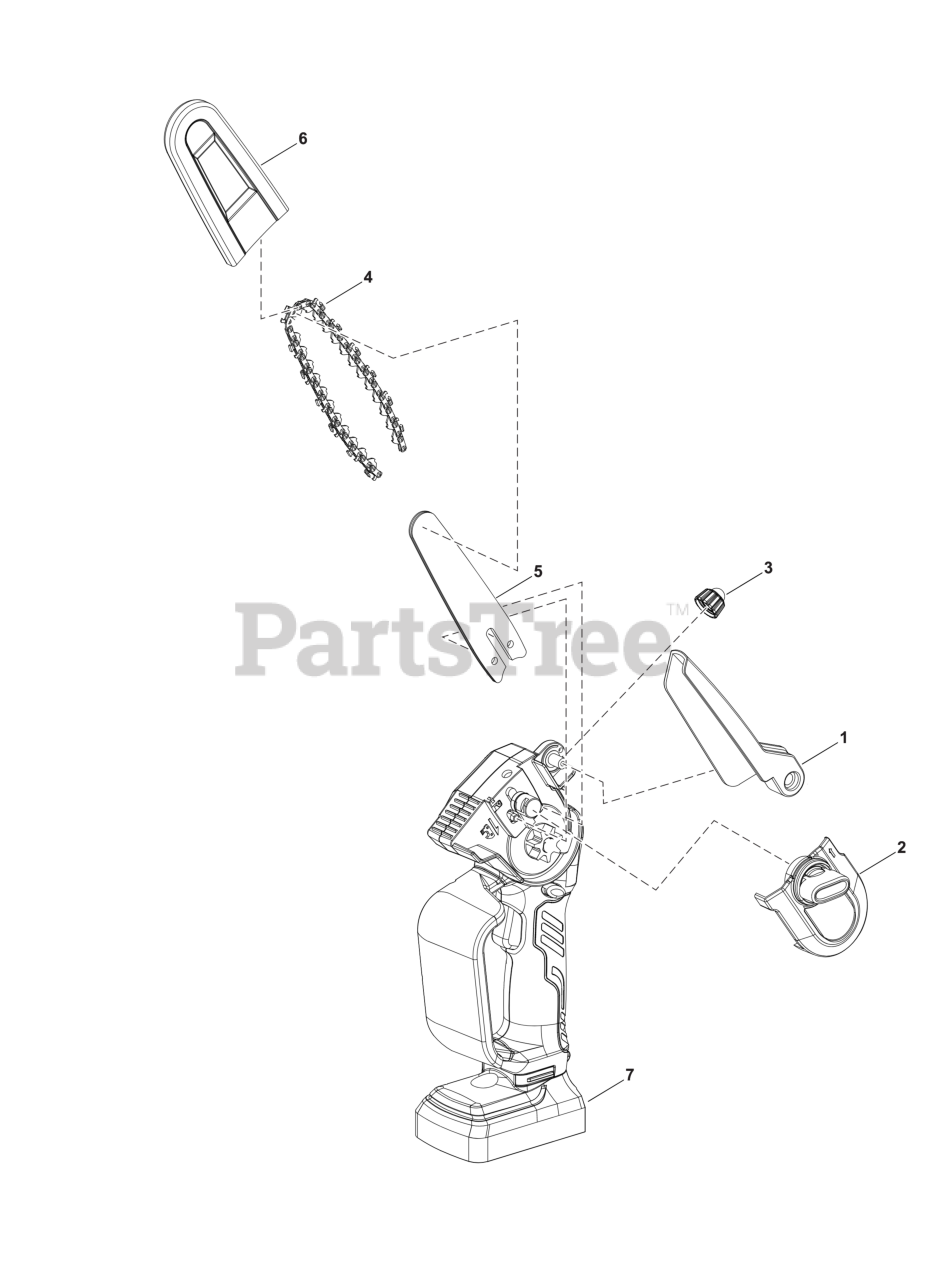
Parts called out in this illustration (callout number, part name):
1	CHAIN GUARD ASSEMBLY
2	CHAIN ADJUSTOR ASSEMBLY
3	OIL KNOB ASSEMBLY
4	18V MINI CHAINSAW CHAIN
5	BAR 5 INCH
6	CHAIN COVER
7	MAIN BODY ASSEMBLY
